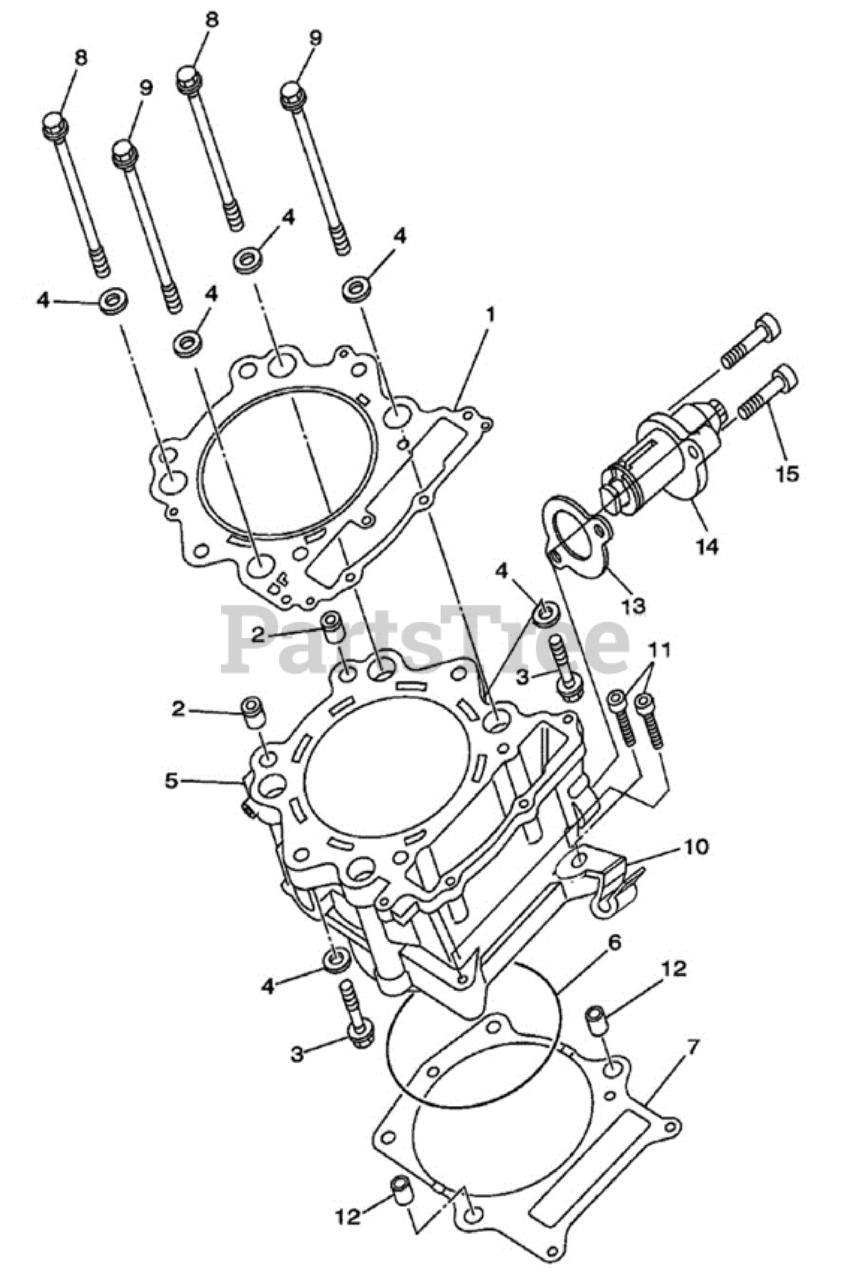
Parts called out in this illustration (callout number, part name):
1	Gasket,Cylinder Head
2	Pin,Dowel 12X16
3	Cylinder bolts M9X1.25X39
4	Washer 10X19X2
5	Cylinder Body assy
6	O-Ring 105.7X2.8
7	Gasket,Cylinder Body
8	Cylinder bolts M10X1.25X121
9	Cylinder bolts M10X1.25X128
10	Pipe Clamp
11	Hexagon socket head cap screws M6X40
12	Pin,Dowel 14X16
13	Gasket,Tensioner
14	Tensioner
15	Hexagon socket head cap screws M6X25
